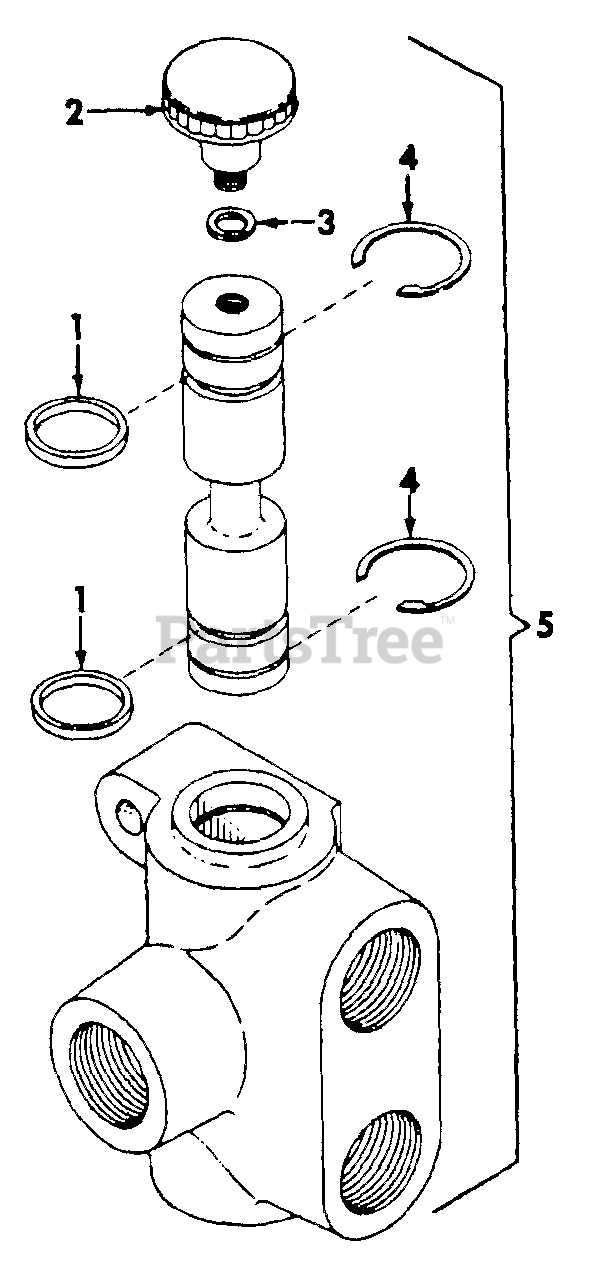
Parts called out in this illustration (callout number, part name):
1	O-RING, 9/16 X 3/4 X 3/32
2	KNOB, CONTROL
3	WASHER, 3/8 C-Z HEAVY LOCK
4	RING, SELECTOR VALVE RETAINING
5	VALVE ASSY, SELECTOR
